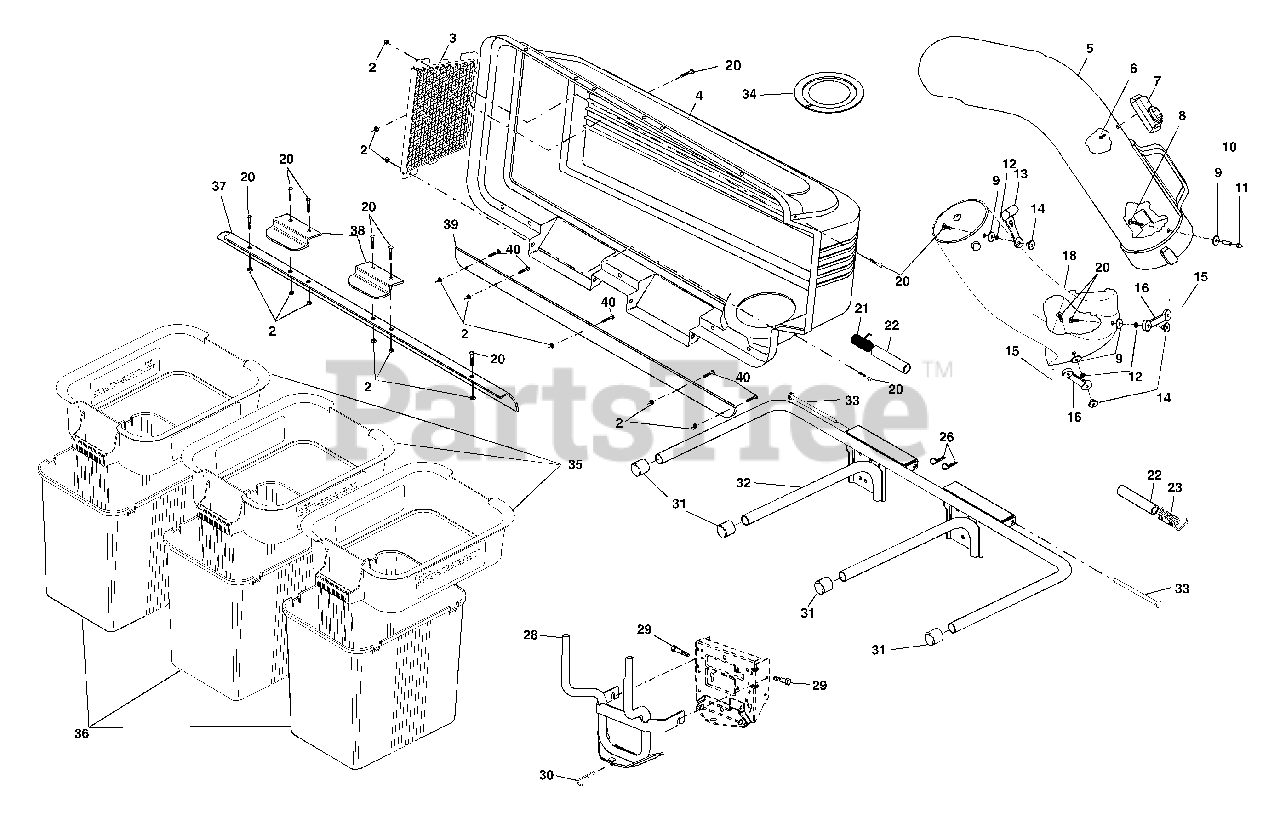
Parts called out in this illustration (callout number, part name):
2	Nut, Crownlock #10-24
3	Screen, Cover
4	Cover
6	Screw, Special #10-14x1/2
7	Dump Bag Indicator
8	Screw, #10-24 x 1-1/8
9	Washer 3/16x3/4x16 Ga.
10	Spacer, Split
11	Nut, Acorn #10-24
14	Nut, Weld
15	Latch, Hook
16	Rubber, Latch
20	Screw #10-24 x 5/8
21	Spring, Cover L.H. (black)
22	Spacer, Cover
23	Spring, Cover R.H. (gray)
26	Spring, Retainer
28	Support Assembly
29	Shoulder Bolt, Self Tapping
30	Spring, Retainer
31	Plug, Tubing End
32	Bagger, Frame
33	Pin, Hinge
34	Gasket, Cover
35	Container, Top
36	Container, Bottom
38	Latch Handle, Cover
39	Strip, Reinforcement
40	Screw #10-24 x 1/2
